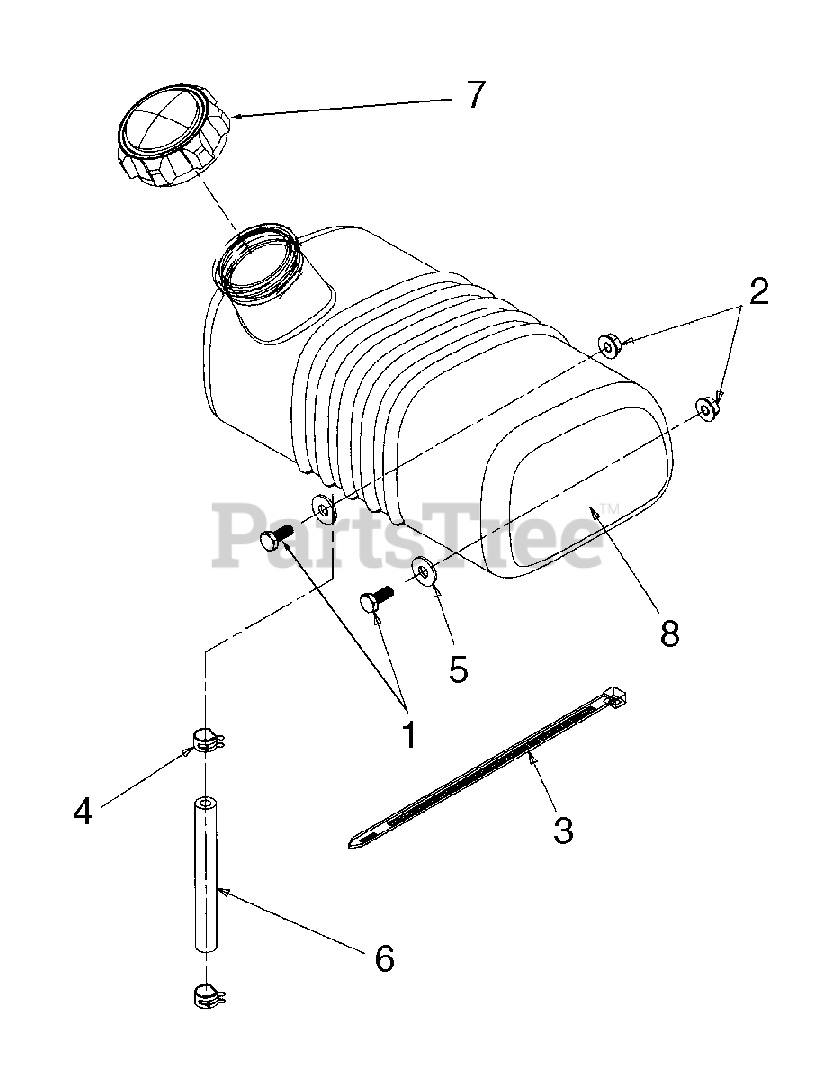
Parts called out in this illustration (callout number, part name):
1	Screw, Hex Cap, 1/4-20 x .62
2	Nut, Hex Flange Lock, 1/4-20
3	Cable Tie, 30.66 Lg
4	Clamp, Hose, 1/2 Inch
5	Washer, Flat, .28 x .74 x .063
6	Hose, Fuel Line 9 Inch
7	Cap, Fuel
8	Tank, Fuel
